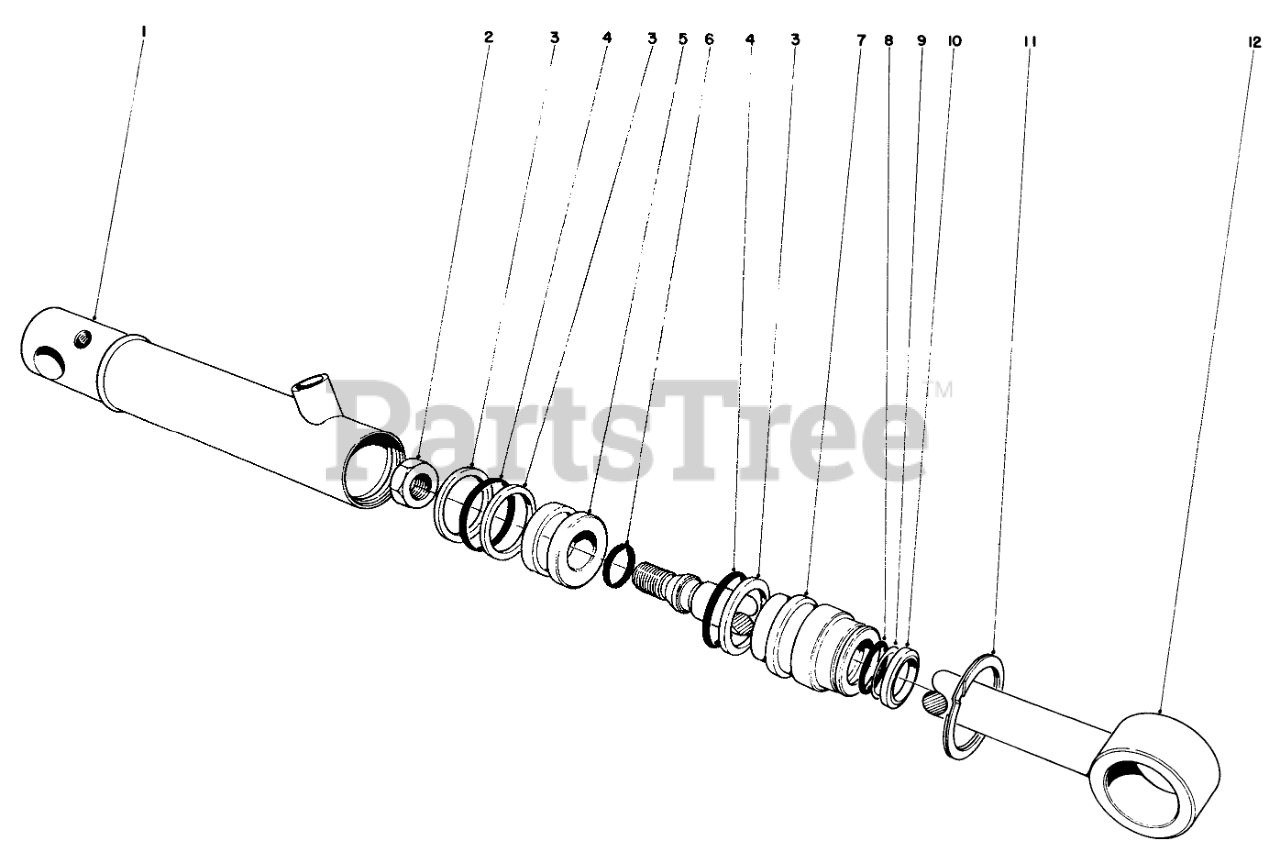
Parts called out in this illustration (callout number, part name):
1	Tube Assembly
2	Nut
3	Back Up Washer
4	O-Ring Piston
5	PISTON
9	Leather
10	Dust Seal
11	RING-RETAINING
12	SHAFT W/CLEVIS
